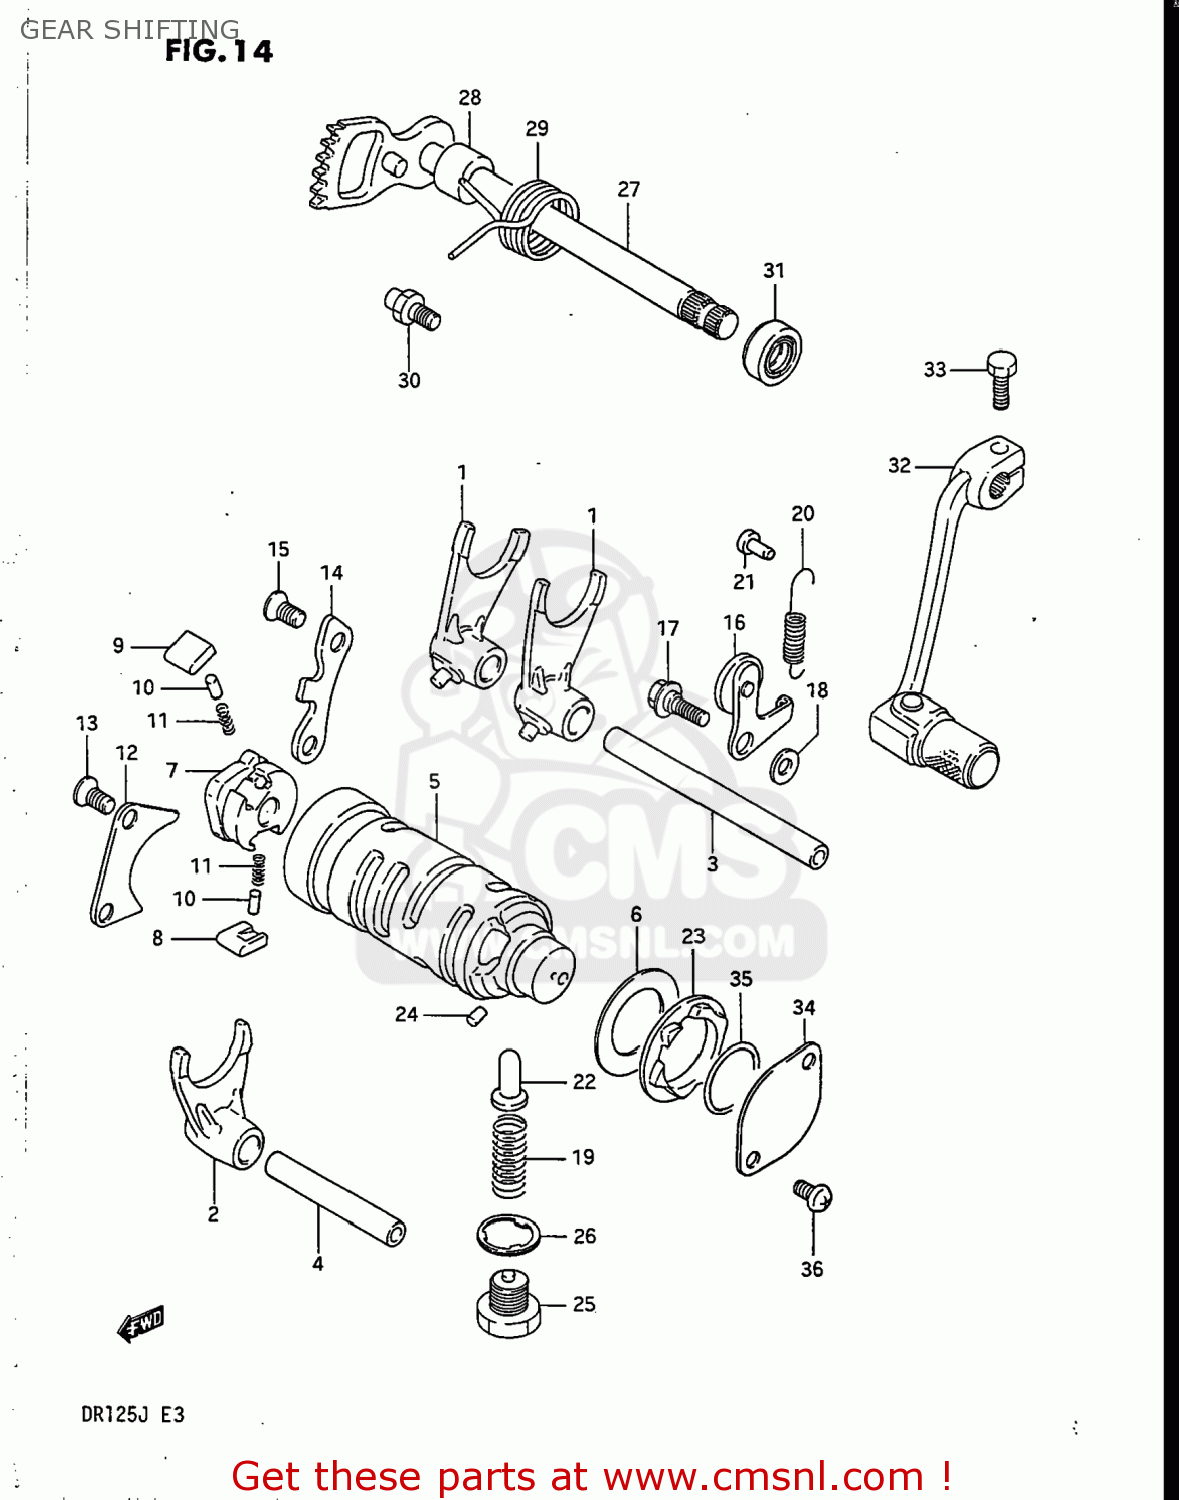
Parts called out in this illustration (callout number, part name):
1	FORK,GEAR SHIFT NO.1
2	FORK,GEAR SHIFT NO.3
3	SHAFT,GEAR SHIFT FORK(L:109)
4	SHAFT,GEAR SHIFT FORK
5	CAM,GEAR SHIFT
6	WASHER,THRUST
7	GEAR,GEARSHIFT CAM DRIVE
8	PAWL,GEAR SHIFT NO.1
9	PAWL,GEAR SHIFT NO.2
10	PIN(5X8)
11	SPRING
12	LIFTER,GEAR SHIFT POLE
13	SCREW
14	GUIDE,GEAR SHIFT CAM
15	SCREW
16	STOPPER,GEAR SHIFT CAM
17	BOLT
18	WASHER
19	SPRING
20	SPRING
21	RIVET
22	STOPPER,GEAR SHIFT CAM NO.2
23	PLATE,GEAR SHIFT CAM STOPPER
24	PIN 4X6
25	PLUG (14X12)
26	GASKET(14X19.2X2) (NAS)
27	SHAFT,GEAR SHIFT
28	SPACER(12X20X15.3)
29	SPRING
30	STOPPER,GEAR SHIFT CAM
31	OIL SEAL
32	LEVER ASSEMBLY,GEAR SHIFTING
33	BOLT
34	CAP,GEAR SHIFT CAM PIVOT
35	O-RING (D:2.4 ID:22.2)
36	SCREW
